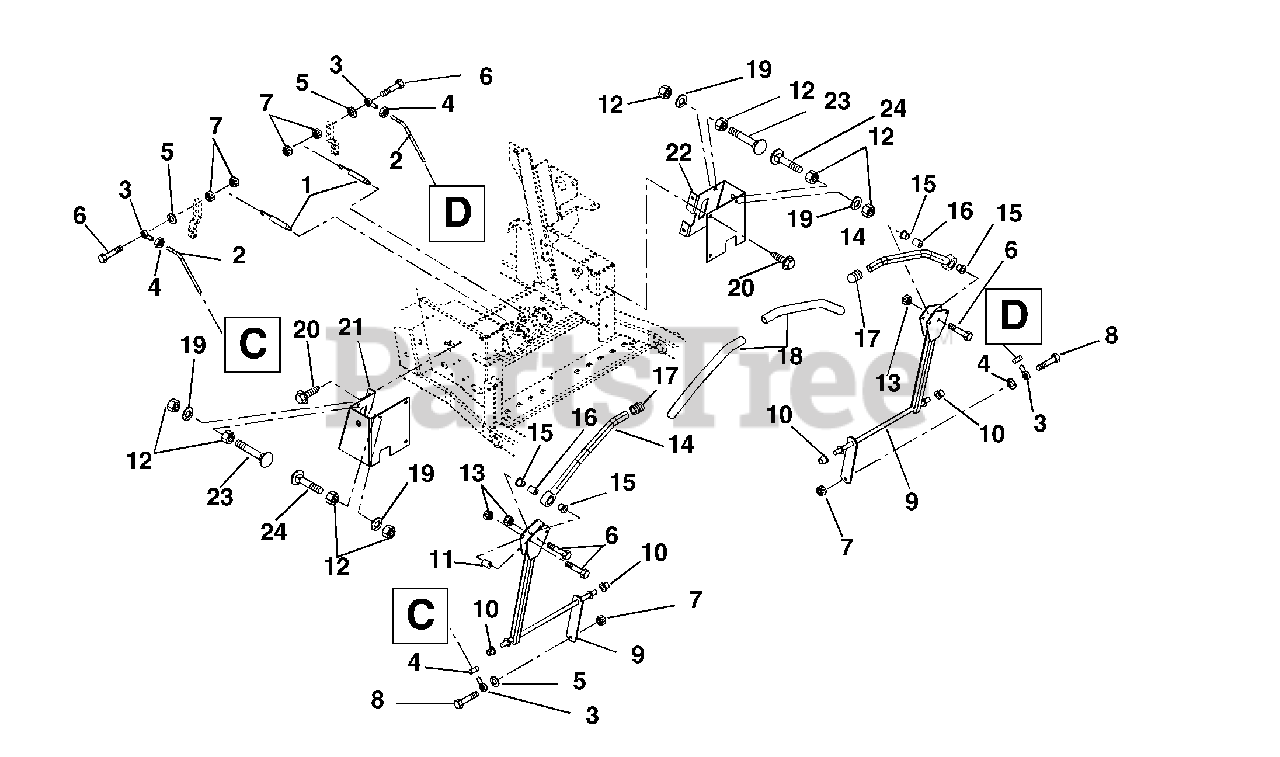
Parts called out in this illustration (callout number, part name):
1	Spring-Tension .062 x .56 x 8.0
2	Rod-Steering Adjustment
3	Rod End .312 Right-Hand-Female
4	Nut-Jam .31-24
5	Washer-Locking .31 x .078
6	Bolt-Hex .31-18 x 1.75 Grade 5
7	Nut-Locking-Center .31-18
8	Bolt-Hex .31-18 x 1.50 Grade 5
9	Rod-Steering
10	Bushing-Flange .515 x .750 x .745 x 1.00
11	Eccentric
12	Nut-Hex .38-16
13	Nut-Locking-Center .31-18
14	Handle Weldment Left-Hand
14	Handle Weldment Right-Hand
15	Bushing-Flange-Nylon .762 x 1.48 x .44
17	Caplug- Handlebar
18	Grip-Handlebar
19	Washer-Locking .38 x .094
20	Screw-Tapping .38-16 x .75 Hex Washer Head
21	Mount-Steering Rod-Right Hand
22	Mount-Steering Rod-Left Hand
23	Bolt-Round Head Square Neck .38-16 x 2.00
24	Bolt-Round Head Square Neck .38-16 x 1.50
